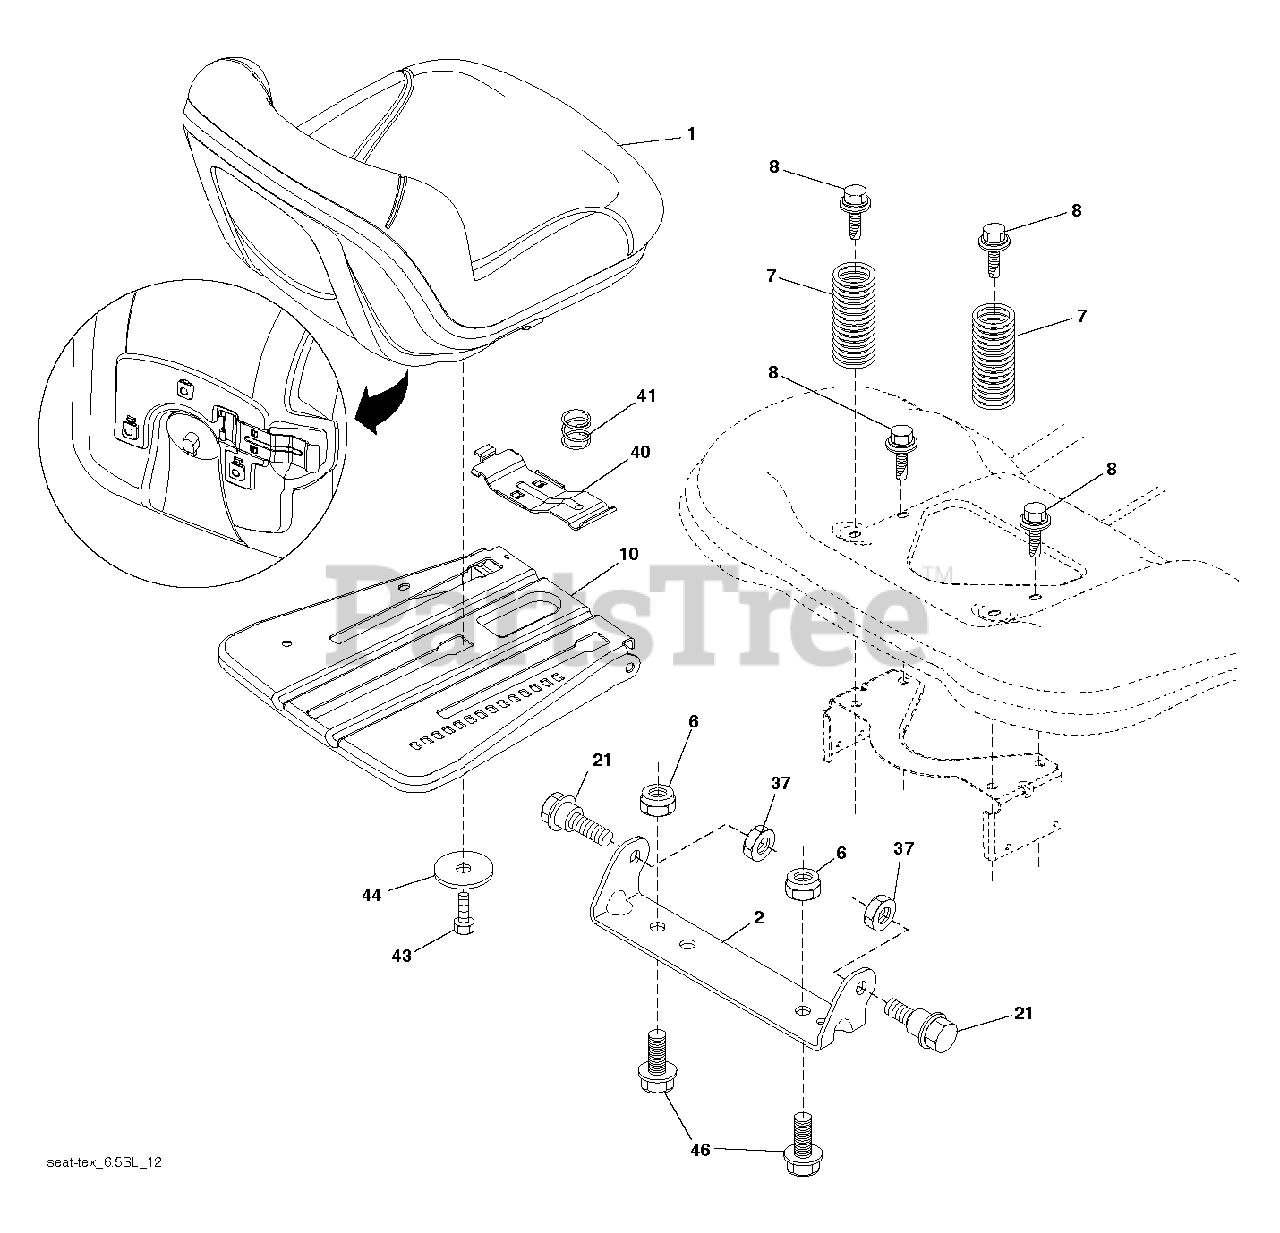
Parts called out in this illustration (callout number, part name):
1	SEAT.TH150.MS498.GRY.HUSQ.TEX
2	BRKT.PIVOT.FENDER
6	NUT
7	SPRING.COMPRESS.SEAT.
8	BOLT, 5/16-18 X 1 3/4
10	PAN.ASM.SEAT.3PT
21	BOLT.5/16-18X5/8.SHOULDER
37	NUT.71038.31-18.HEX.NYLOCK
40	HANDLE.SLIDE.SEAT.TEX.GREY
41	SPRING.LATCH.SEAT.TEX
44	WASHER 13/32 X 2-3/8 X 12GA
46	BOLT.3/8-16X1;1.25OD.WSHR.SEMS
